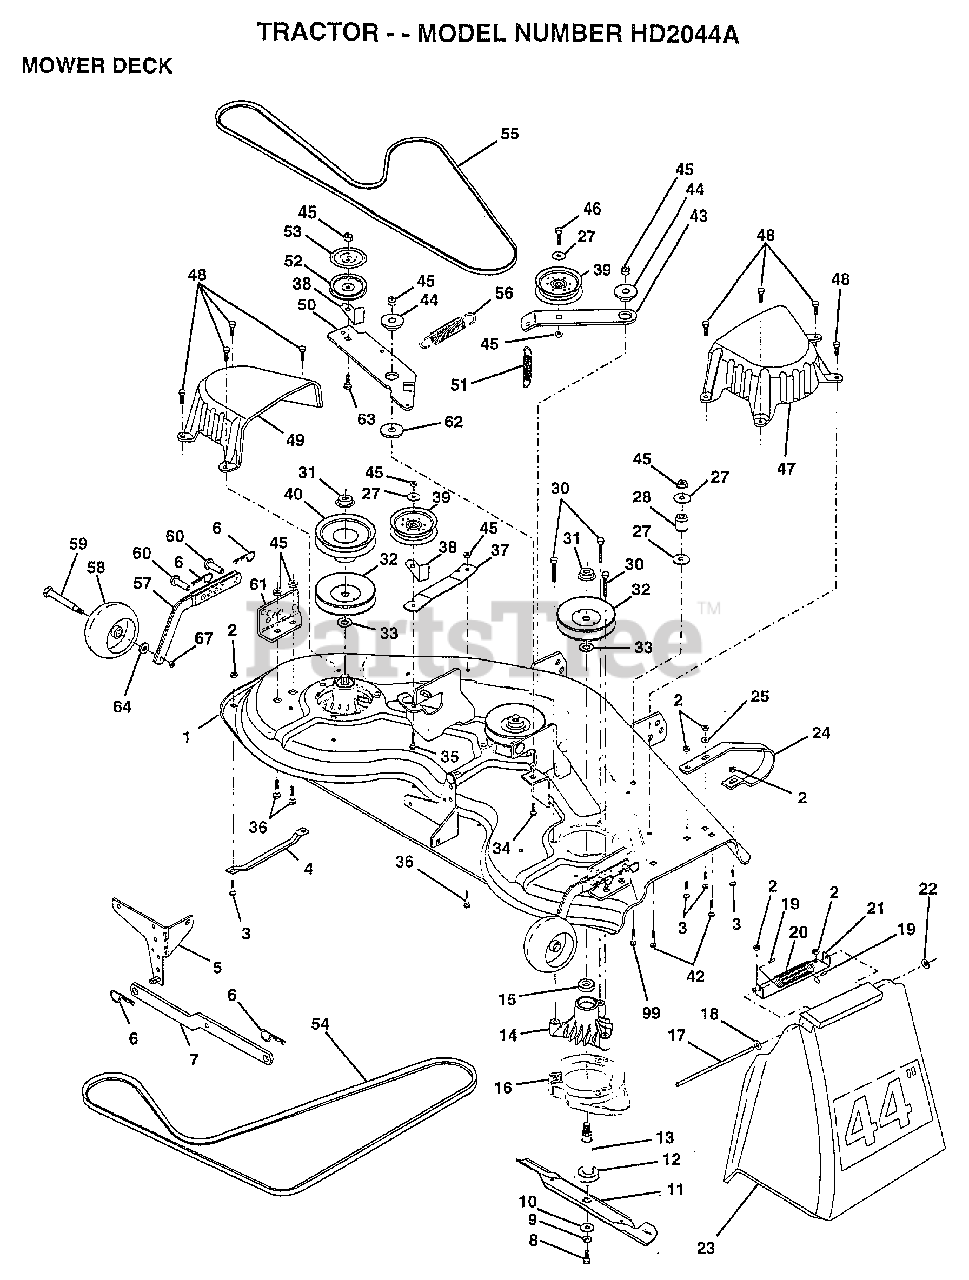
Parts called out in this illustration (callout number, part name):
1	"DECK ASM WELD44"""
4	RUNNER-LH M
5	BRKT.ASM.SW.44/50
8	BLADE BOLT
10	WASHER.HARD.BLADE
11	"BLADE.44"" HIPERF"
12	BEARING.BALL
13	SHAFT.ASM.W/BRNG
14	HOUSING.MAND.44.V
15	BEARING
16	STRIPPER RND MWR
17	ROD-HINGE T
18	WASHER
20	SPRING TORSION
21	BRKT DEFLECTOR
23	DEFLECTOR SHIELD
24	RUNNER.RH
25	WASHER M
27	WASHER
33	WASHER
34	BOLT.3/8-14X1.25
35	BOLT
36	BOLT D
37	STIFFENER.ARM.IDL
39	FLAT IDLER PULLEY
40	"PULLEY.DRIVEN.44"""
42	BOLT
43	"ARM.IDLER.SEC.44"""
44	SPACER RETAINER
47	"COVER.MAND.RH.44"""
48	SCREW.1/4-20X5/8
49	COVER.MANDREL.LH
50	ARM.IDLER.PRIMARY
51	"SPRING.SEC.44""VEN"
52	PULLEY.IDLER.VGRO
53	SHIELD.IDLER.44.V
54	V-BELT.PRIM.78.5.
55	BELT-V.88.12.MW
56	SPRING.EXT.DECK.
57	BAR.ASM.GUAGE.WHL
58	WHEEL.GUAGE.MED.
59	BOLT.SHOULDER
60	PIN.CLEVIS
61	BRACKET.GUAGE.WHL
62	HARDENED WASHER
63	BOLT.3/8-16X1.50
64	WASHER
67	LOCKNUT
99	BOLT
